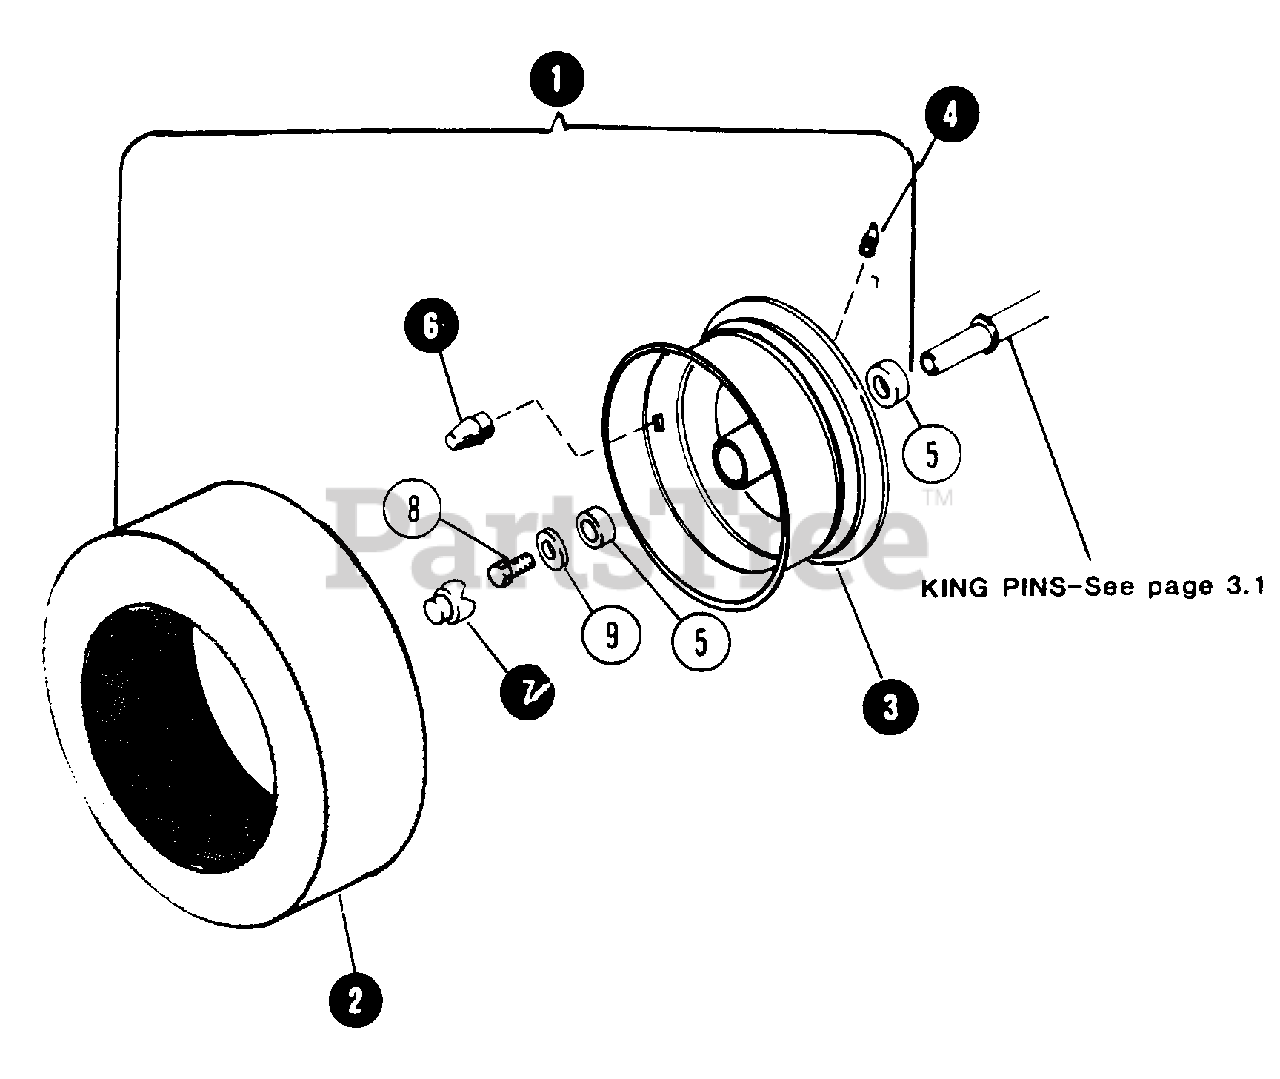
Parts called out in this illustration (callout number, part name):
1	WHEEL ASSEMBLY
2	TIRE, 16 x 6.50 x 8
3	RIM
4	PULLEY, 8.36" O.D.
5	BEARING, BALL
6	VALVE, AIR
7	CAP, FRONT HUB
8	BOLT, 3/8C x 7/8 HEX HEAD
9	WASHER, 13/32" FLAT
